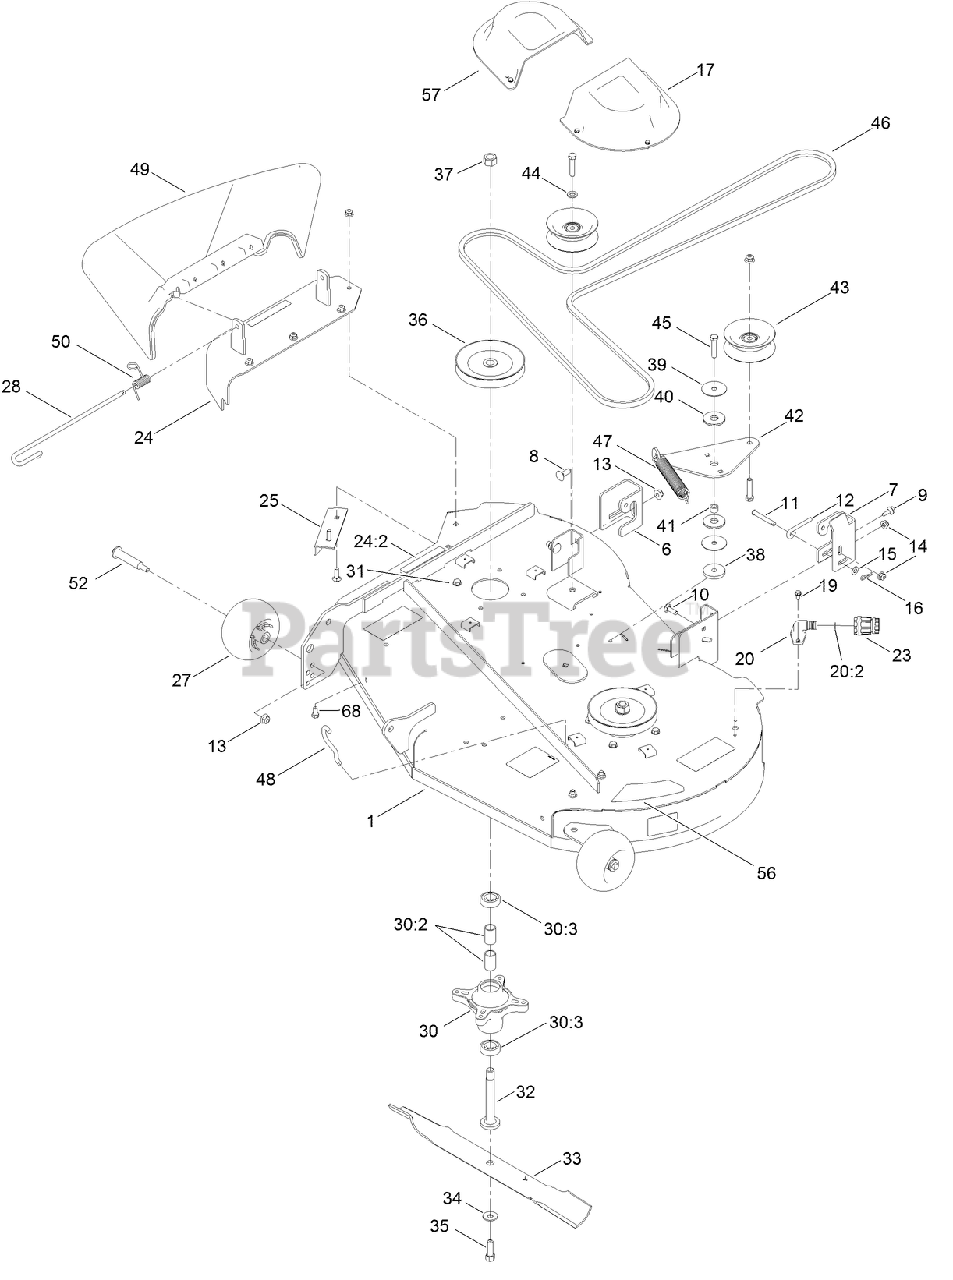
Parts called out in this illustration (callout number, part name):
1	42 INCH DECK ASM
6	BRACKET-HANGER, RH
7	BRACKET-HANGER, LH
8	BOLT-CARR
9	SCREW-SHOULDER,HWH
10	SCREW-CARR
11	PIN-CLEVIS
12	ROD-LEVEL, DECK
13	NUT-HF, NI
14	NUT-HF, NI
15	WASHER-PLAIN
16	PIN-COTTER
17	COVER-BELT
19	SCREW-HWH
20	FITTING-WASHOUT
20:2	O-RING
23	CONNECTOR-HOSE
24	COVER ASM W/DECAL
24:2	DECAL-DANGER
25	BAFFLE-CUTOFF
27	ROLLER-SCALP, ANTI
28	PIN-CHUTE
30	SPINDLE ASM
30:2	SPACER
30:3	BEARING-BALL
31	SCREW-TAPTITE
32	SHAFT-SPINDLE
33	BLADE-HIGH LIFT
34	WASHER-BELLEVILLE
35	SCREW-HH
36	PULLEY
37	NUT-HEX
38	WASHER-PLAIN
39	WASHER
40	WASHER-FRICTION, COMPOSITE
41	SPACER
42	ARM-IDLER
44	WASHER-FLAT
45	SCREW-HH
46	V-BELT
47	SPRING-EXTENSION
48	HOOK-RETURN, SPRING
49	DEFLECTOR-DISCHARGE
50	SPRING-TORSION
52	BOLT-SHOULDER
56	DECAL-DECK
57	SCREW-TAPTITE
68	SCREW-HH
